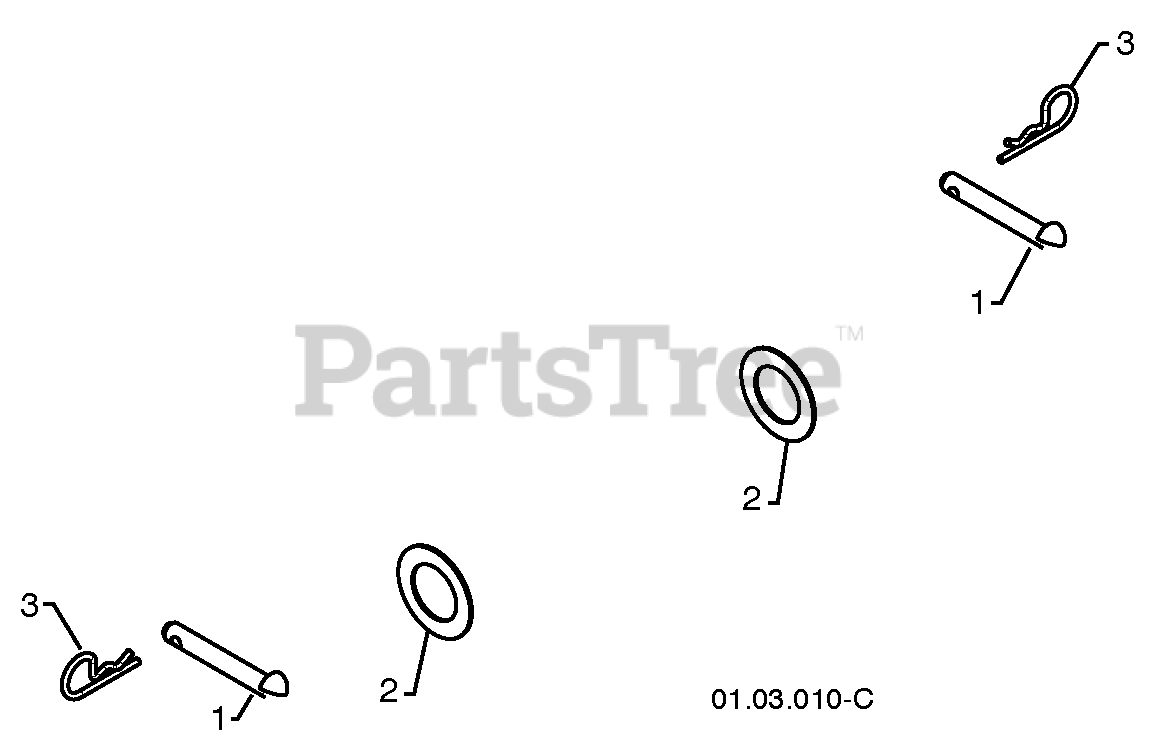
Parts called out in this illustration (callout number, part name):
1	RIVET
2	THRUST WASHER
3	RETAINER M
